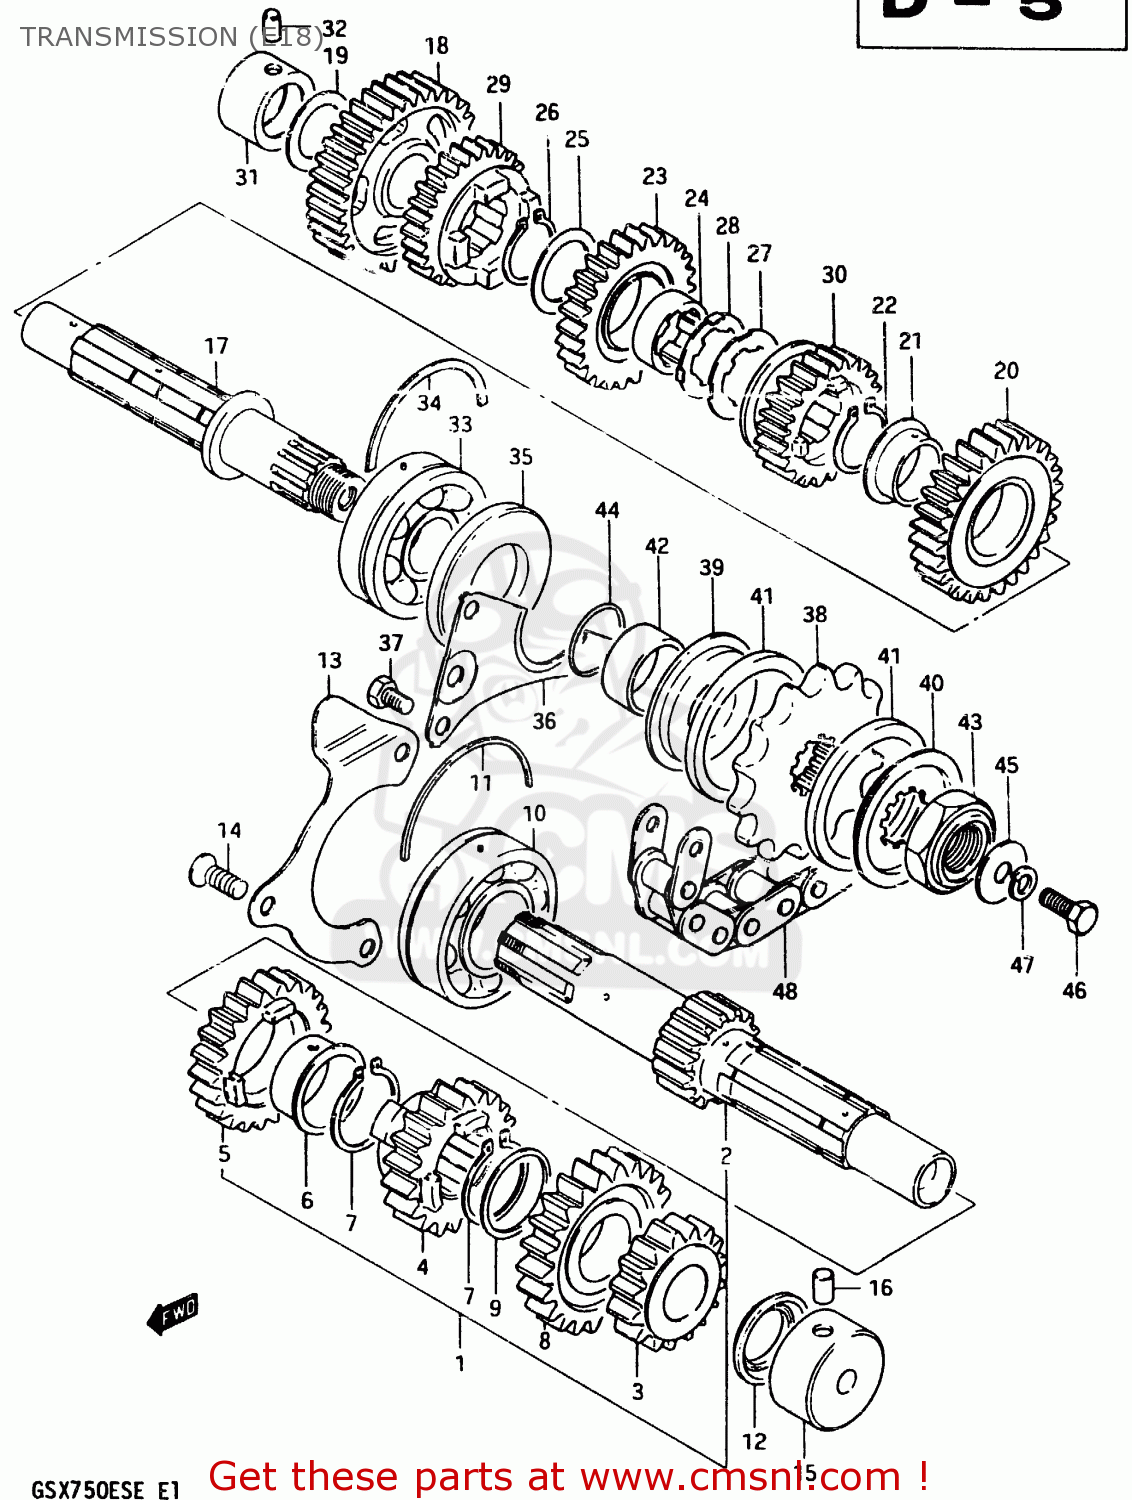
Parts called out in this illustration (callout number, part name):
1	SHAFT,COUNTER
2	SHAFT,COUNTER
3	GEAR,SECOND DRIVE
4	GEAR,THIRD DRIVE
5	GEAR,FOURTH DRIVE
6	BUSH
7	RING,SNAP
8	GEAR,FIFTH DRIVE (NT:23)
9	WASHER,LOCK
10	BEARING(25X62X17)
11	C-RING
12	BEARING(20X47X19.25)
13	PLATE,COUNTERSHAFT BEARING
14	SCREW
15	BEARING(20X34X17.5)
16	PIN
17	SHAFT,DRIVE
18	GEAR,1ST DRIVEN(NT:35)
19	WASHER
20	GEAR,2ND DRIVEN(NT:28)
21	BUSH(28X32X2)
22	CIRCLIP
23	GEAR,THIRD DRIVEN
24	BUSH,3RD DRIVEN GEAR
25	WASHER,LOCK
26	CIRCLIP
27	WASHER,LOCK
28	WASHER
29	GEAR,FOURTH DRIVEN
30	GEAR,5TH DRIVEN(NT:22)
31	BEARING(20X34X20)
32	PIN
33	BALL BEARING 25X62X17
34	C-RING
35	SEAL,OIL(33X62X7)
36	PLATE,DRIVESHAFT OIL
37	BOLT
38	SPROCKET,ENGINE
39	HOLDER, SPROCKET, NO.1
40	HOLDER,SPROCKET DAMPER
41	DAMPER,SPROCKET
42	SPACER
43	NUT
44	O RING(D:1,ID:24.5)
45	WASHER
46	BOLT, UPPER
47	LOCK WASHER
48	CHAIN ASSEMBLY,DRIVE
